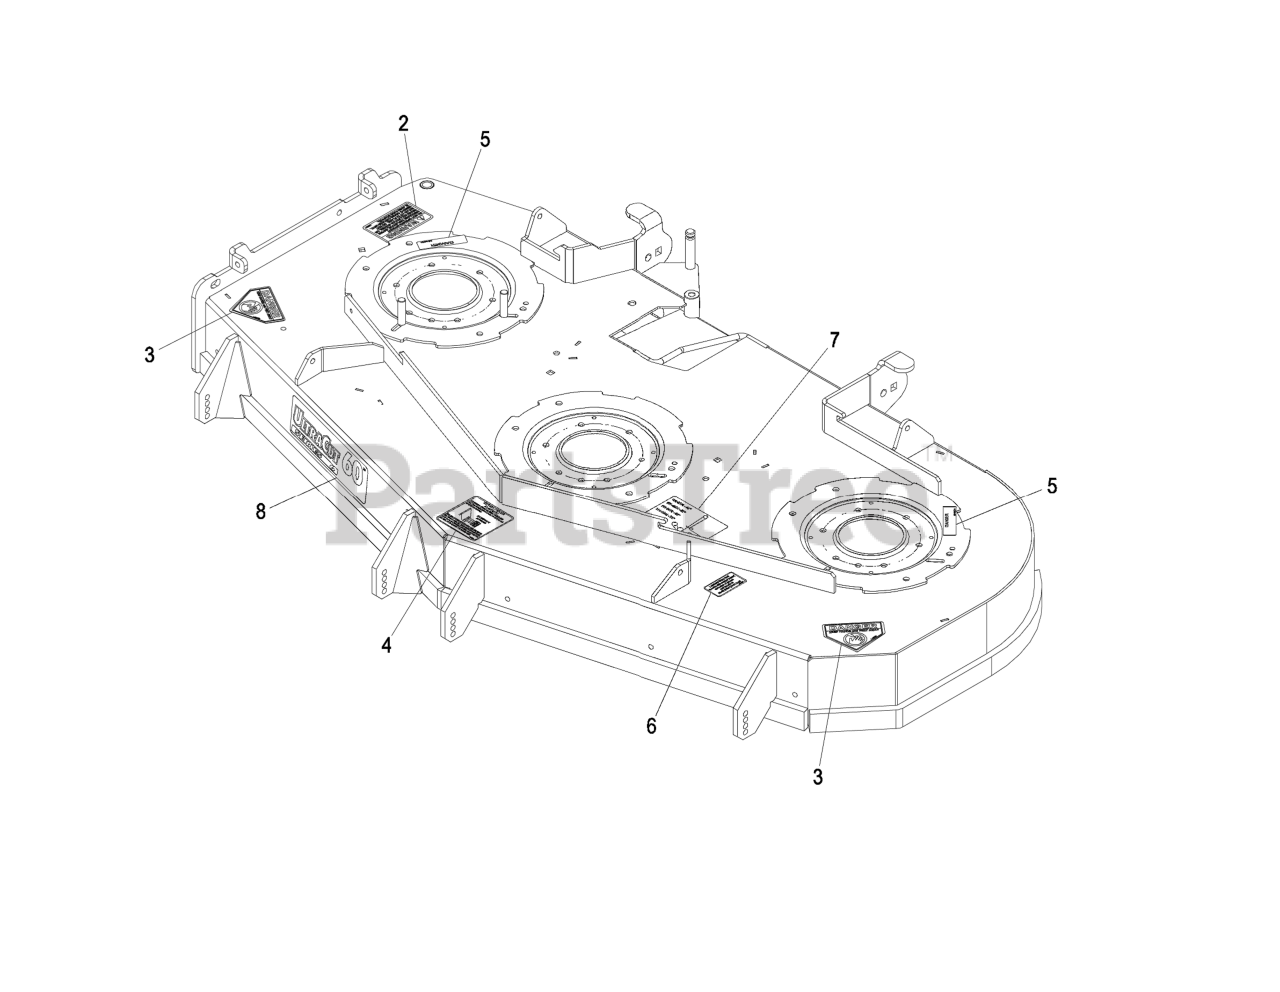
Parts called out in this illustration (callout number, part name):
2	DECAL-WARNING, DISCHARGE
3	DECAL-DANGER
4	DECAL,ANTISCALP
5	DECAL-COVER, MISSING
6	DECAL,BOLT TORQUE
7	DECAL,BELT ROUTING
8	DECAL,ULTRACUT 60 SERIES
